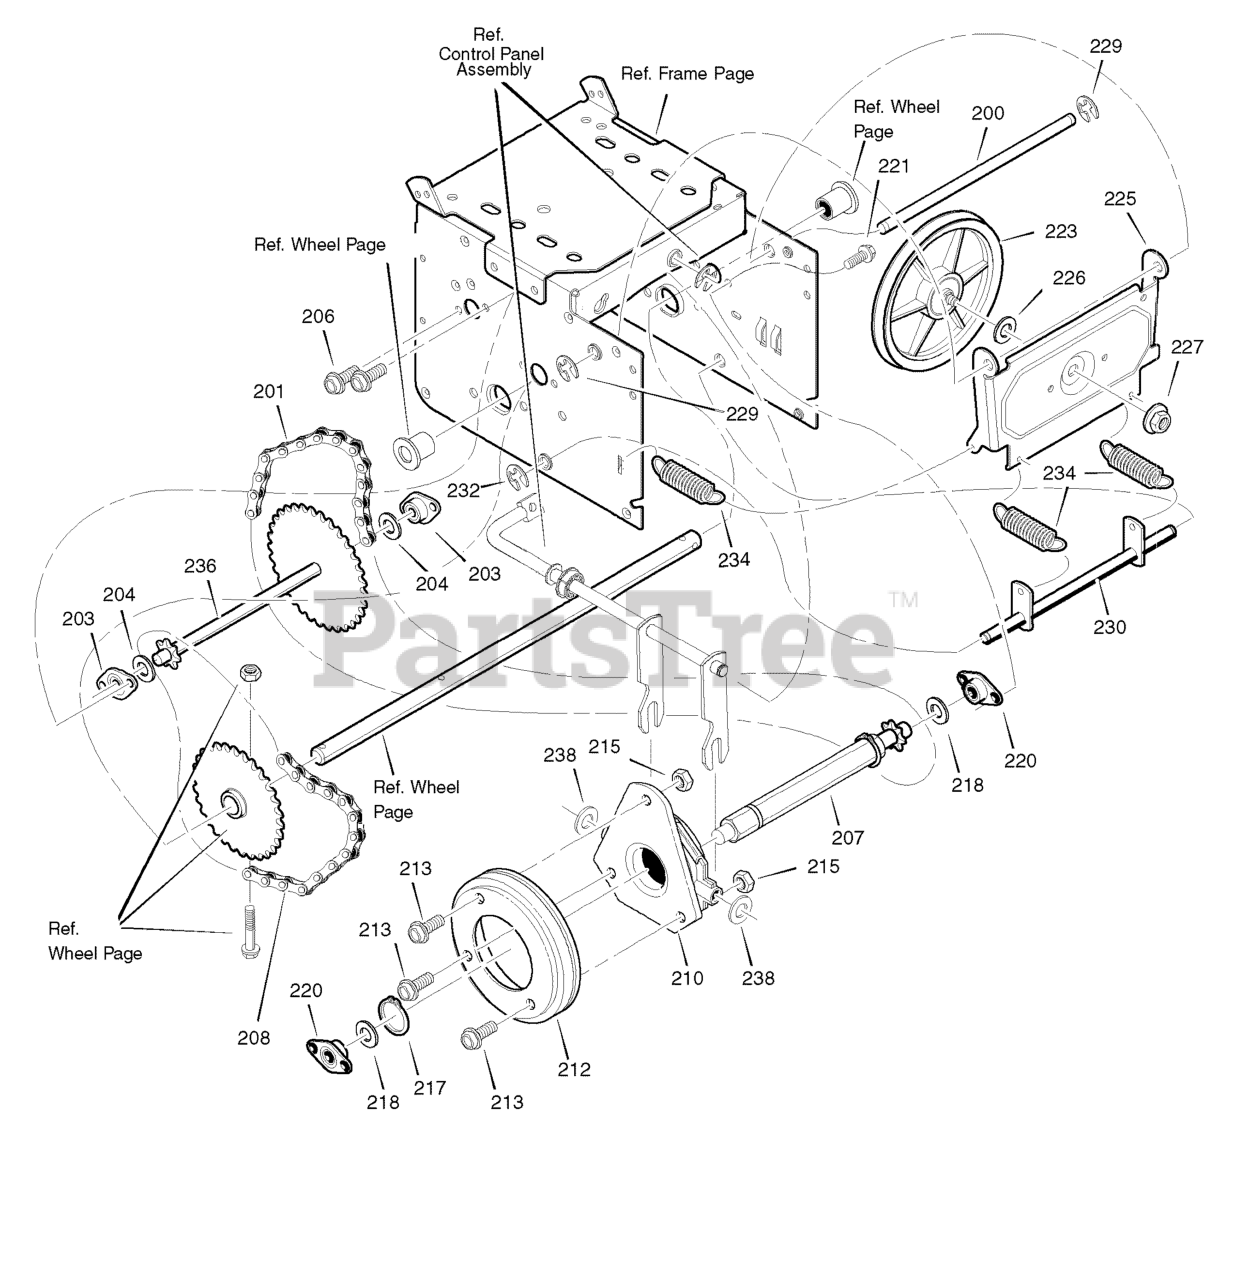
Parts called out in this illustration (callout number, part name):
200	LF AXLE, SWING PLATE YZ
201	CHAIN, ROLLER #420x19.00
203	BEARING AND RETAINER, ASSY
206	SCREW, TAP 5/16-18 x 0.5
207	ASSY, HEX SHAFT
208	CHAIN, ROLLER #420x18.00 LG
210	BEARING, TRUNION CLUTCH R
212	WHEEL, FRICTION DISC
215	NUT, KEPS HEX 1/4-20
217	RING, RETEXT
220	BEARING AND RETAINER, ASSY
221	SCREW, TAP 5/16-18 x .5
223	ASSEMBLY, FRICTION PULLY
225	LF PLATE, SWINGING YZ
226	SPACER, FRICTION PULLEY
227	NUT, FLANGE LOCK 3/8-24
229	RETAINER, RING
230	LF ASSY, SPRING LINK YZ
232	RETAINER, RING
234	SPRING, EXTENSION
236	WLD, INTERMED SPROCKET 33T/7
238	WASHER, FLAT
